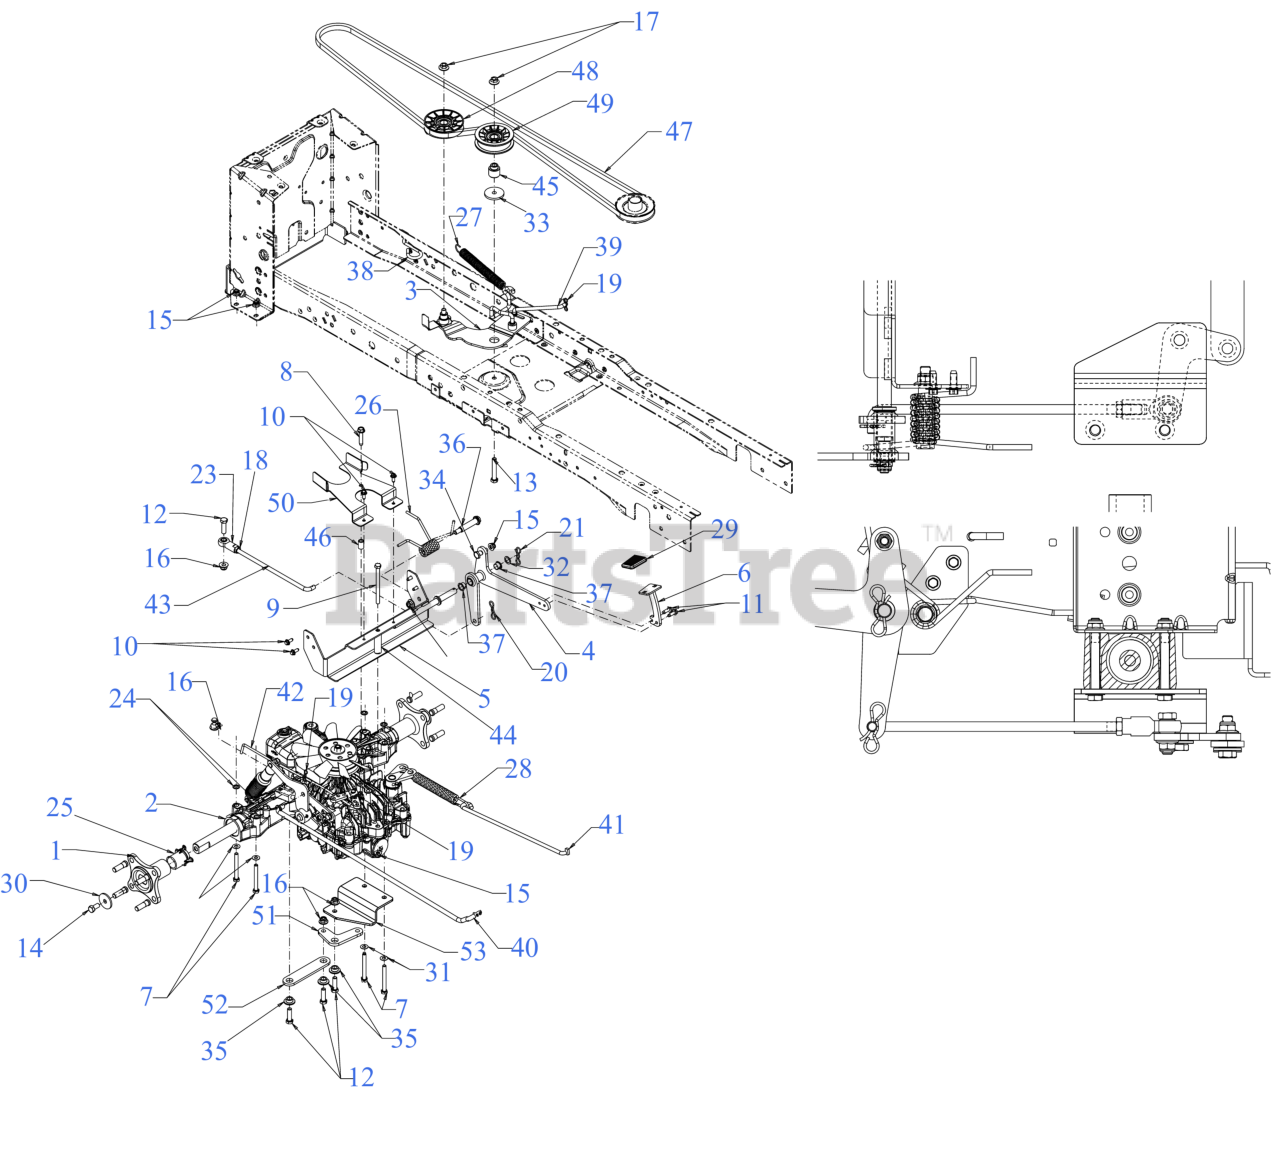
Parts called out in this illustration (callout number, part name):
1	WHEEL HUB ASSEMBLY
1	STUD 7/16-14 x 1.6
2	HYDRO TRANS ASSEMBLY
3	IDLER BRACKET ASSEMBLY
4	DIFF PEDAL PIVOT ASSEMBLY (PLATED)
6	DIFF LOCK PEDAL ASSEMBLY (PLATED)
7	HEX SCREW 5/16-18 x 2.75
8	HEX SCREW WASHER 5/16-18 x 1.5
9	SCREW 5/16-18 x 4.00 GR5
10	SCREW M6-1 x .625
11	SCREW 1/4-20 x .750
12	SCREW 3/8-16 x 1.25 GR5
13	SCREW 3/8-16 x 2.25 GR5
14	SCREW 3/8-16 x .75 GR 5
15	FLANGE LOCK NUT 5/16-18
17	FLANGE LOCK NUT
18	HEX JAM NUT 3/8X24
19	BOW TIE COTTER PIN 1/4-5/16
20	PIN:COTTER
21	BOW TIE COTTER PIN
23	ROD END 3/8 ID
25	AXLE SLEEVE 1.02 ID x 1.60 LG
26	DIFF PEDAL TORSION SPRING
27	EXTENSION SPRING .790 DIA x 8.41
28	EXTENSION SPRING 0.90 DIA x 8.14
29	DIFF LOCK PEDAL PAD
30	FLAT WASHER .390x1.500x.134
31	FLAT WASHER
32	THRUST WASHER
33	SHOULDER SPACER
34	SHOULDER SCREW
35	SHOULDER SPACER
36	SHOULDER BOLT (.50 X 2.0 x 3/8 -16)
37	NYLINER BEARING
38	DECK SPRING HOOK
39	IDLER BRACKET ROD
40	HYDRO CONTROL ROD (PLATED)
41	BRAKE CONTROL ROD (PLATED)
42	HYDRO DISENGAGE ROD (TUFF TORQ)
43	ROD .344 OD x 9.68 LG
45	SHOULDER SPACER
46	SLEEVE .33X.50X.75 LG
47	V-BELT A SEC x 90.00
48	V-IDLER PULLEY 3.56 OD
49	FLAT IDLER PULLEY 3.00 OD
51	PIVOT BELLCRANK (PLATED)
52	BELLCRANK LINK (PLATED)
53	BELLCRANK MOUNTING BRACKET (PLATED)
